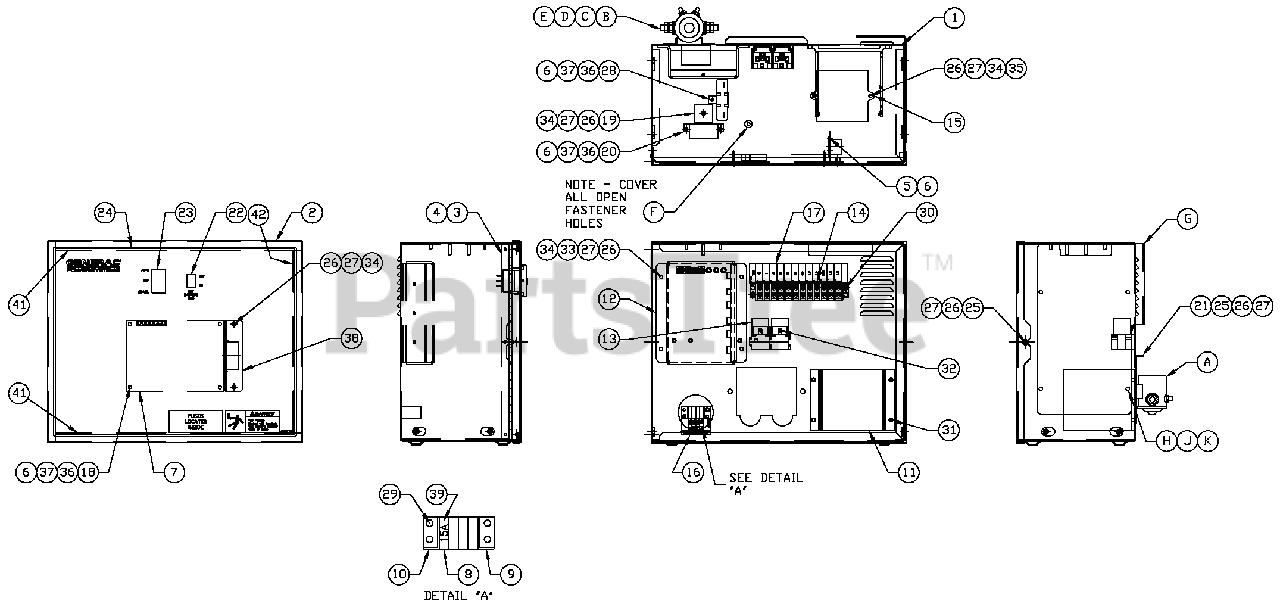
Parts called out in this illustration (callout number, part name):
1	ENCL HSB CONTROL PANEL
2	COVER CONTROL PANEL
3	HINGE CONTINUOUS H-PANEL
4	RIVET POP .125 X .275 SS
5	SCREW PHM M3-0.5 X 10MM
6	WASHER FLAT M3
7	ASSY PCB CPL CTRLR 1800 RPM
8	HOLDER FUSE WICKMANN 178.6150
9	ADPTR RH SIDE WICKMAN 178.6191
10	ADPTR LH SIDE WICKMAN 178.6192
11	ASSY PCB 2AMP 12V UL BATT CHGR
12	ASSY VOLTAGE REGULATOR 60HZ
13	RELAY 12VDC C FORM W/DIODE
14	BLOCK TERM 20A 12 X 6 X 1100V
15	ASSY PCB BOSCH GOV DRIVER
16	DECAL CPL CONTROL PANEL FUSES
17	DECAL CPL 3.9L TB1
18	SPACER 9.5H 3.2 ID
19	DIO BRIDGE 25A 600V
20	CIRCT BRK 7 X 1 ETA 46-500-P
21	PLATE,HARNESS CLAMP
22	SWITCH RKR DPST 125V SPD
23	SWITCH RKR DPDT ON-OFF-ON
24	DECAL CONTROL HSB
25	SCREW HHPM M5-0.8 X 12
26	WASHER FLAT M5
27	WASHER LOCK M5
28	RES WW 15R 5% 25W QK CONN
29	SCREW PHTT M3.5-0.6 X 10
30	SCREW PHTT M3.5-0.6 X 16
31	SCREW PHTT M4-0.7 X 12 ZYC
32	SCREW PHTT M4-0.7 X 10 ZYC
33	SCREW PPHM M5-0.8 X 12 ZNC
34	NUT HEX M5-0.8 G8 CLEAR ZINC
35	SCREW PPHM M5-0.8 X 30 SS
36	WASHER LOCK M3
37	NUT HEX M3-0.5 G8 YEL CHR
38	SUPPORT ANGLE PCB
39	FUSE ATO TYPE 15 AMP (BLUE)
41	SEAL COVER 3.18 X 12.7 X 382
42	SEAL COVER 3.18 X 12.7 X 283
A	RELAY SOLENOID 12VDC PNL MNT
B	SCREW HHC M6-1.0 X 16 G8 .8
C	WASHER FLAT 1/4-M6 ZINC
D	WASHER LOCK M6-1/4
E	NUT HEX M6 X 1.0 G8 YEL CHR
F	SEAL WEATHER .45"DIA
G	COVER CONTROL PANEL SIDE
H	SCREW HHC M5-0.8 X 16 G8 .8
J	WASHER LOCK M5
K	WASHER FLAT #10 ZINC
